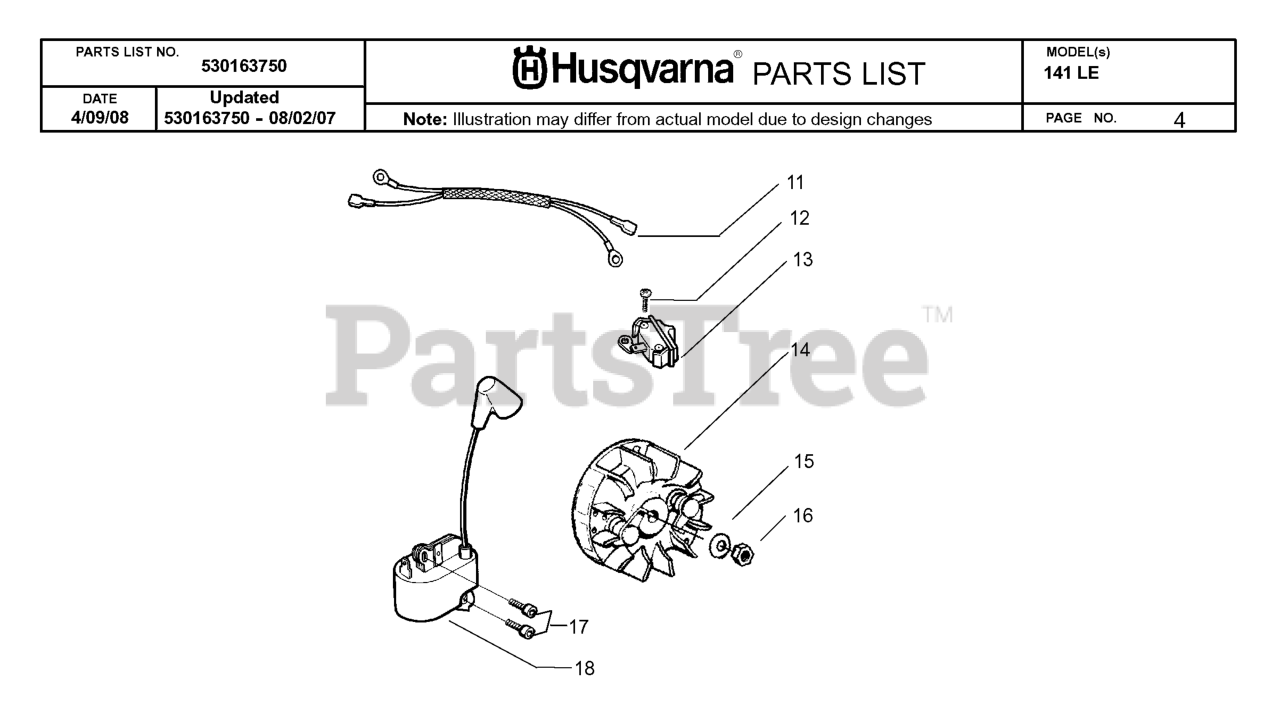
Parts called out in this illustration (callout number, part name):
11	LEAD WIRE ASSY
13	SWITCH ON/OFF
14	ROTOR COMPL. 36/41
15	WASHER-FLYWHEEL
18	%IGNITION MODULE
